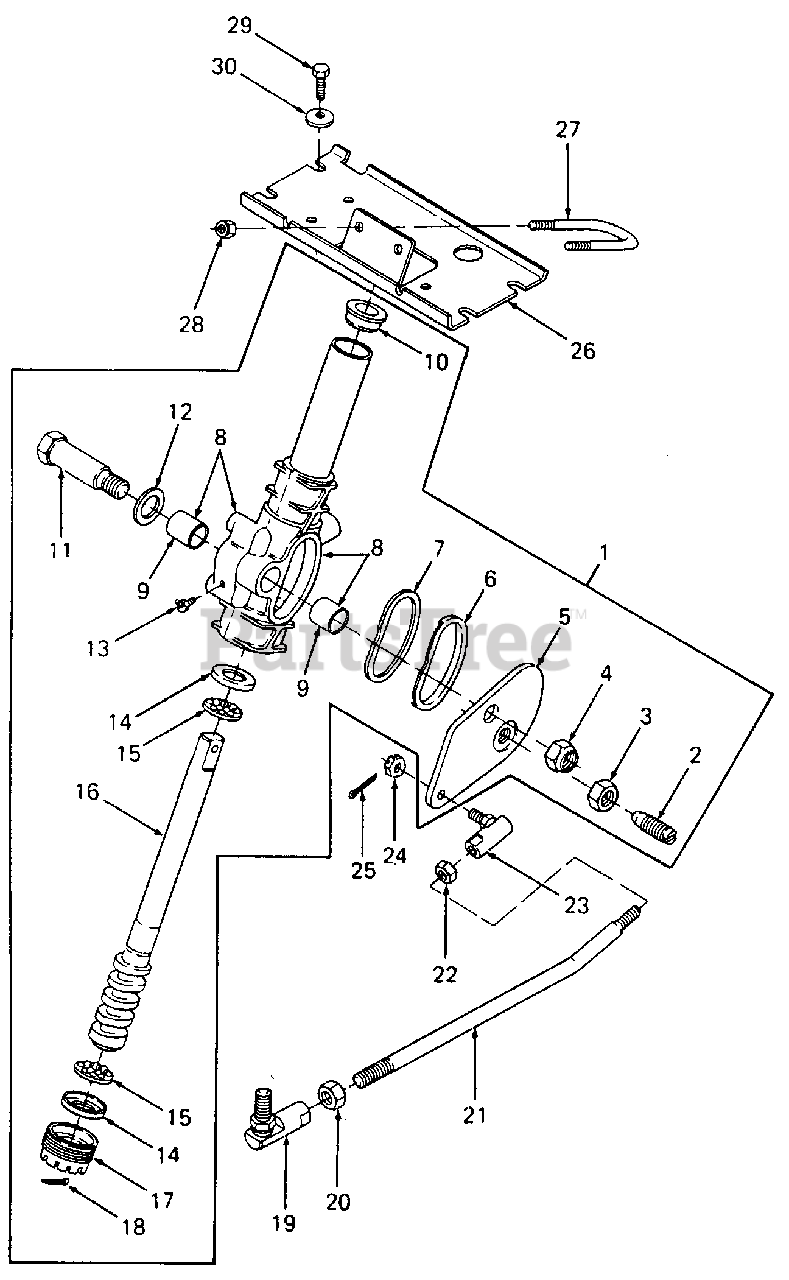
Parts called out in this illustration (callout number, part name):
1	Steering Gear Assy
2	Follower, Cam
3	Nut, Hex Jam, 9/16-18
4	Nut, Hex Crown Lock, 5/8-18
5	Arm, Steering
6	Retainer, Seal
7	Seal
8	Housing/Tube Assy
10	Bearing, Column
11	Shaft, Pivot
12	Washer, Flat, .781 X 1.25 X .027 Thk
13	Fitting, Lube, 45 Deg 1/4-28 Taper
14	Cup, Bearing
15	Retainer Assy, Ball
16	Shaft/Cam Assy
17	Plug, Adjusting
18	Pin, Cotter, 1/8 Dia X .75 Lg
19	Ball Joint
20	Nut, Hex Jam, 1/2-20 GR5
21	Link, Drag
22	Nut, Hex Jam, 3/8-24 GR5
23	Ball Joint
24	Nut, Hex Castle, 3/8-24 GR5
25	Pin, Cotter, 3/32 Dia X .75 Lg
26	Plate, Steering Support
28	Nut, Hex Center Lock, 5/16-24
29	Screw, Hex Hd Cutting, 5/16-18 X .75 Lg
30	Washer, Bell, .345 X .88 X .060 Thk
